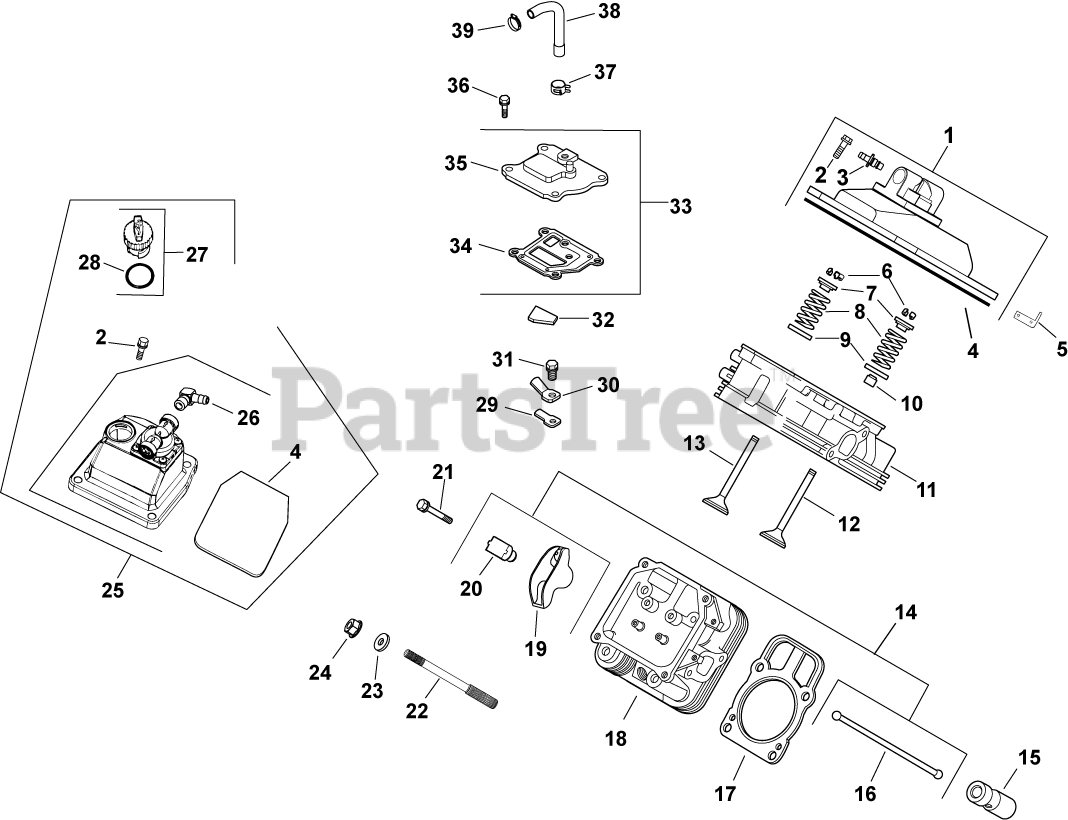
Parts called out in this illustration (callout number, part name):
1	KIT, VALVE COVER-PLAIN
2	SCREW, FLG M6X1.0X30
3	KIT, STRAIGHT FITTING
4	O-RING (YELLOW), VALVE COVER
5	STRAP, LIFT
6	KIT, RETAINER
7	CAP, VALVE SPRING
8	SPRING, VALVE
9	RETAINER, SPRING
10	SEAL, VALVE STEM - (#2503214S)
11	KIT, CYLINDER HEAD #1 - (#24318143S)
12	VALVE, INTAKE (STD)
13	VALVE, EXHAUST (STD) - USE 32 016 01-S
14	KIT, VALVE TRAIN
15	LIFTER, VALVE HYDRAULIC - (#2535111S)
16	ROD, PUSH
17	KIT, CYLINDER HEAD GASKET
18	KIT, CYLINDER HEAD #2 USE 24 318 149-S
19	ARM, ROCKER
20	PIVOT, ROCKER ARM
21	SCREW, FLG M6X1.0X34
22	STUD, M8X1.25
23	WASHER, FLAT 8.6 MM
24	NUT, FLG M8X1.25
25	KIT, VALVE COVER-FUEL PUMP
26	KIT, 90 DEG. FITTING
27	CAP ASSY, OIL FILL (YELLOW)
29	REED, BREATHER
30	RETAINER, REED
31	SCREW, FLG THD FRM M5X.8X10
32	FILTER, BREATHER
33	KIT, BREATHER ASSEMBLY
34	GASKET, BREATHER
35	KIT, BREATHER ASSEMBLY
36	SCREW,FLG THD FRM M6X1.0X20-(#25086396S)
37	CLAMP, HOSE (KM)-USE 25 237 31-S
38	HOSE, BREATHER
39	CLAMP, BAND SPRING HOSE-(#2523737S)
2401602-S	VALVE, EXHAUST (.25)
2401702-S	VALVE, INTAKE (.25)
